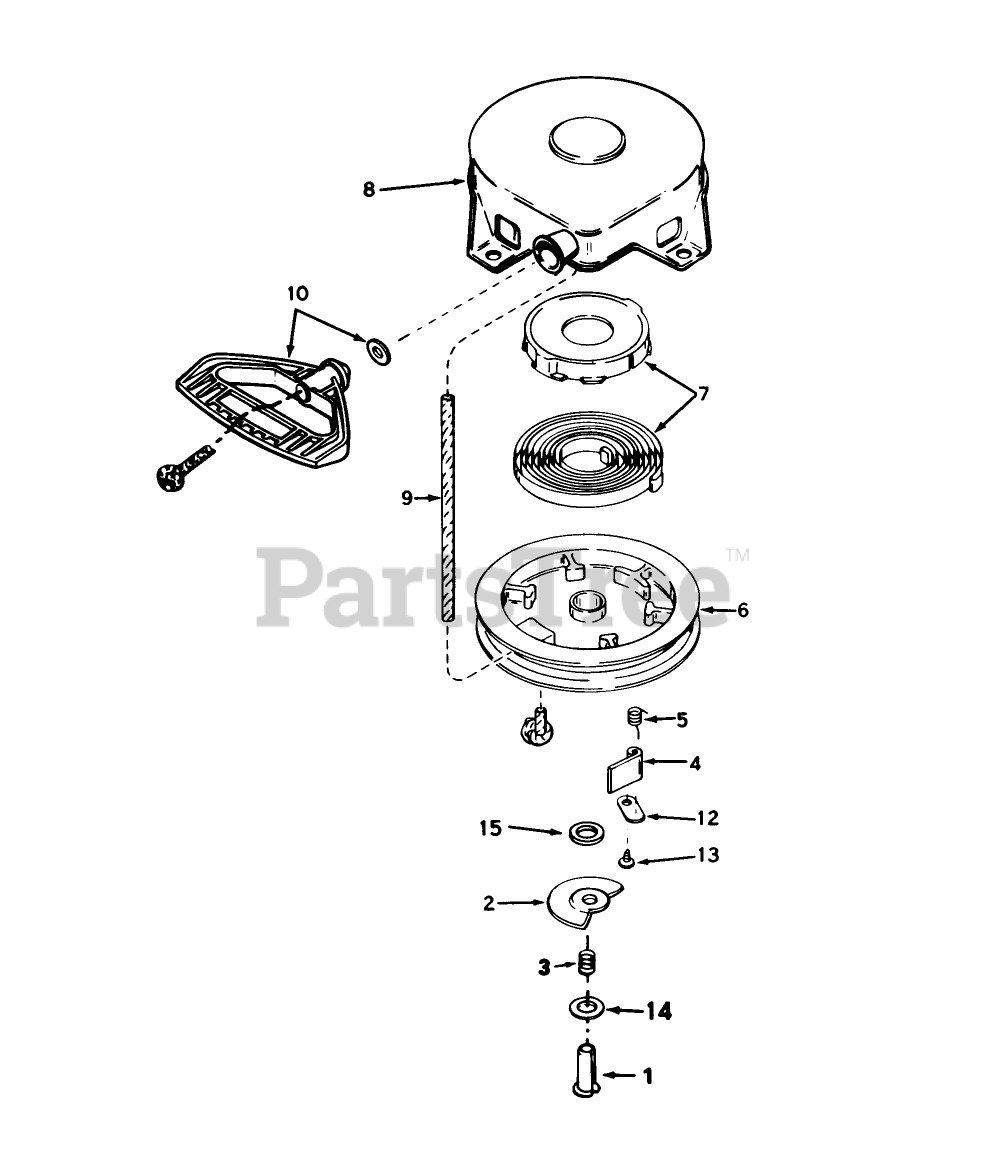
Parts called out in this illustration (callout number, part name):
1	Pin Spring
2	Washer
3	Brake Spring
4	Dog-Starter
5	Spring-Dog
6	Pulley
7	Spring Keeper Assy
8	Housing-Starter
9	Rope-Starter
10	Handle-Starter, Mitten Grip
12	Retainer-Dog
13	Screw
14	Washer
15	Washer
